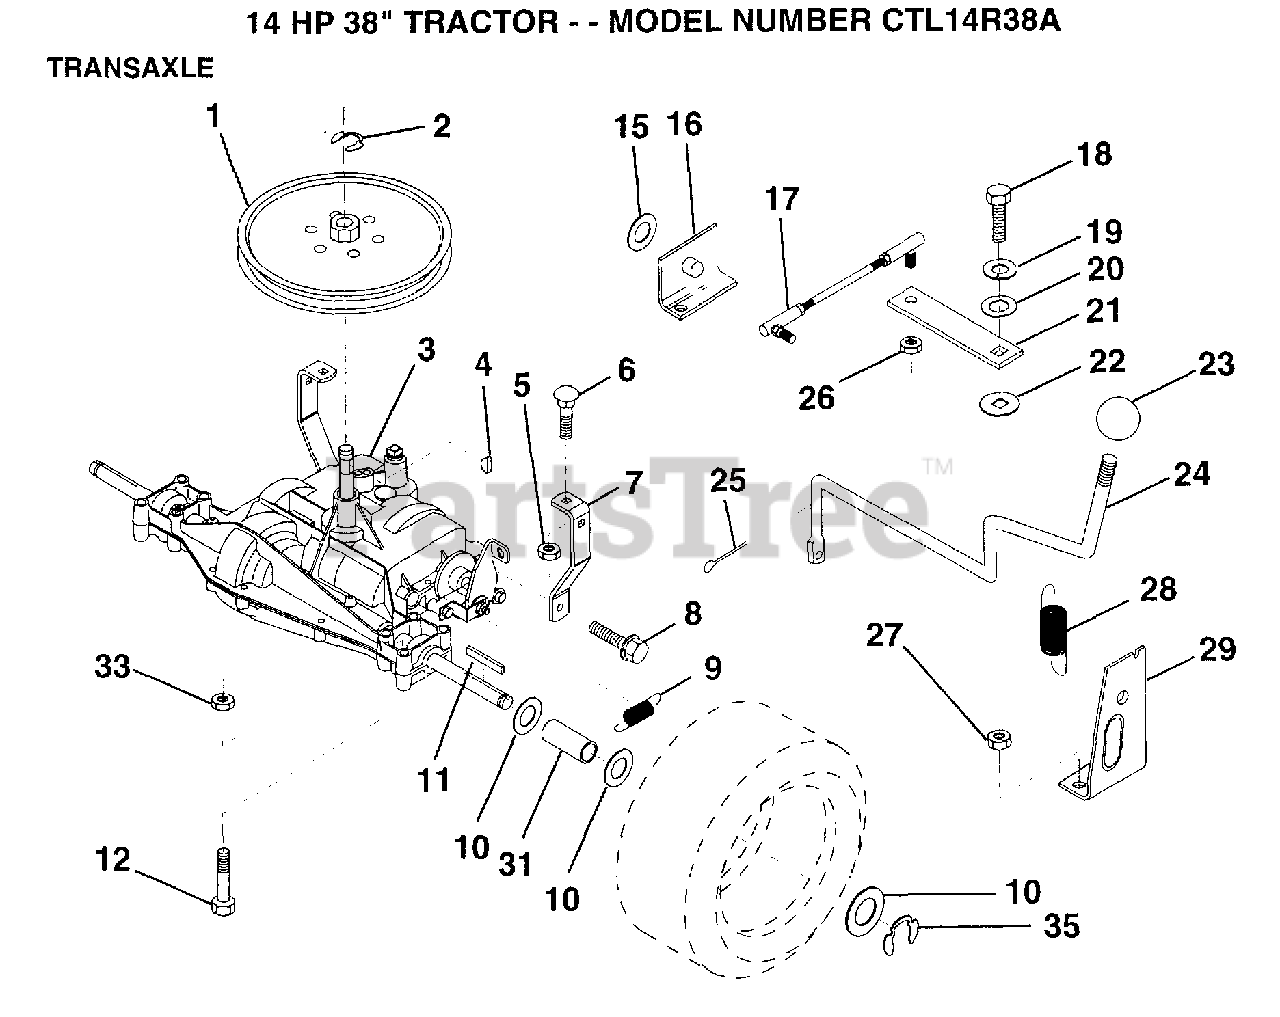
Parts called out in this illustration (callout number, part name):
1	PULLEY
5	NUT
6	BOLT
7	"STRAP,TORQUE"
8	SCREW
10	WASHER
11	SQUARE KEY
12	BOLT
16	"SUPT,HDLE SHT LH"
17	"LINK,SHIFT"
19	LOCKWASHER
20	WASHER LT
21	"ARM,SHIFT"
22	WASH-SHFT PLT LT
23	KNOB.DUCKHEAD.1/2
24	"ROD,SHIFT"
25	PIN COTTER 1/8
26	NUT.LOCK.5/16-24
28	"SPRING,EXT"
29	"SUPT,HDLE RH"
30	KNOB RETAINER
31	SPACER LT
33	NUT
35	E-RING LT
